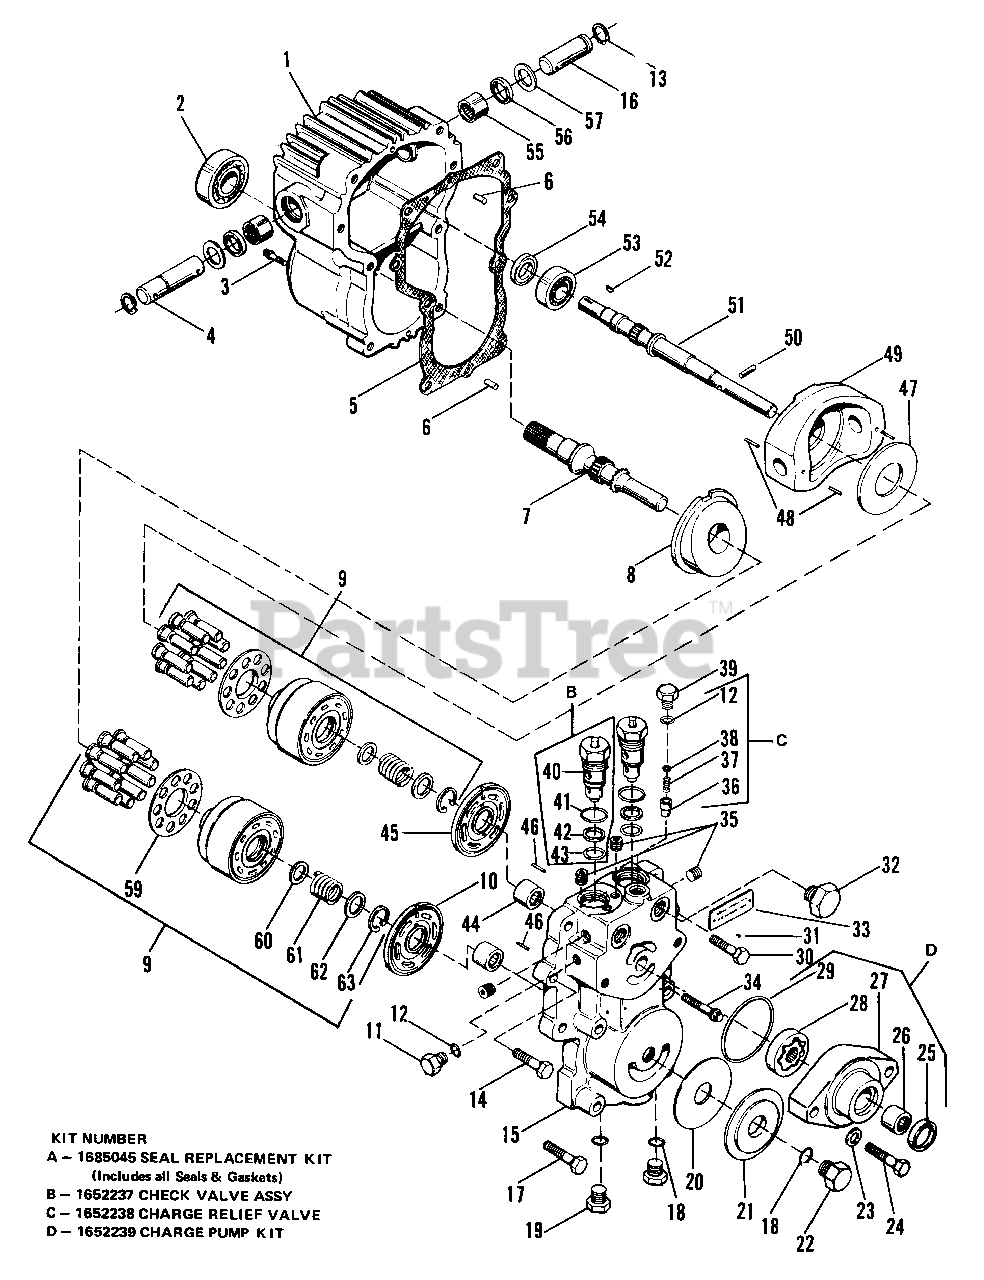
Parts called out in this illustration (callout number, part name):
2	BEARING, Ball
3	CAPSCREW, 12 Pt.
6	PIN, Str. Headless
7	SHAFT, Motor
8	PLATE, Swash
9	* CYLINDER BLOCK KIT
10	VALVE, Plate
11	PLUG, Hex Hd.
13	RING, Retaining
14	CAPSCREW, Hex Hd.
15	SECTION, Center
17	CAPSCREW, Hex Hd.
19	PLUG, Hex Hd.
21	COVER PLATE, Filter
22	PLUG, Special
23	WASHER, Flat
24	CAPSCREW, Hex Hd.
26	BEARING, Needle
27	HOUSING, Charge Pump
28	GEROTOR ASSY
30	CAPSCREW, Hex Hd.
31	SCREW, Drive
32	PLUG, Str. Thd., Hex
33	PLATE, Name
34	CAPSCREW, 12 Pt.
36	CONE, Relief Valve
37	SPRING, Relief Valve
39	PLUG, Hex Hd.
40	CHECK VALVE ASSY
42	RING, Back-up
44	BEARING, Needle
45	PLATE, Valve
46	PIN, Str. Headless
47	PLATE, Thrust
48	PIN, Coiled Spring
49	PLATE, Swash
50	PIN, Str. Headless
51	SHAFT, Pump
52	KEY, Woodruff
53	BEARING, Ball
55	BEARING, Needle
57	WASHER, Special
59	RETAINER, Slipper
60	WASHER, Front
62	WASHER, Rear
63	RING, Retaining
64	SEAL & GASKET KIT
